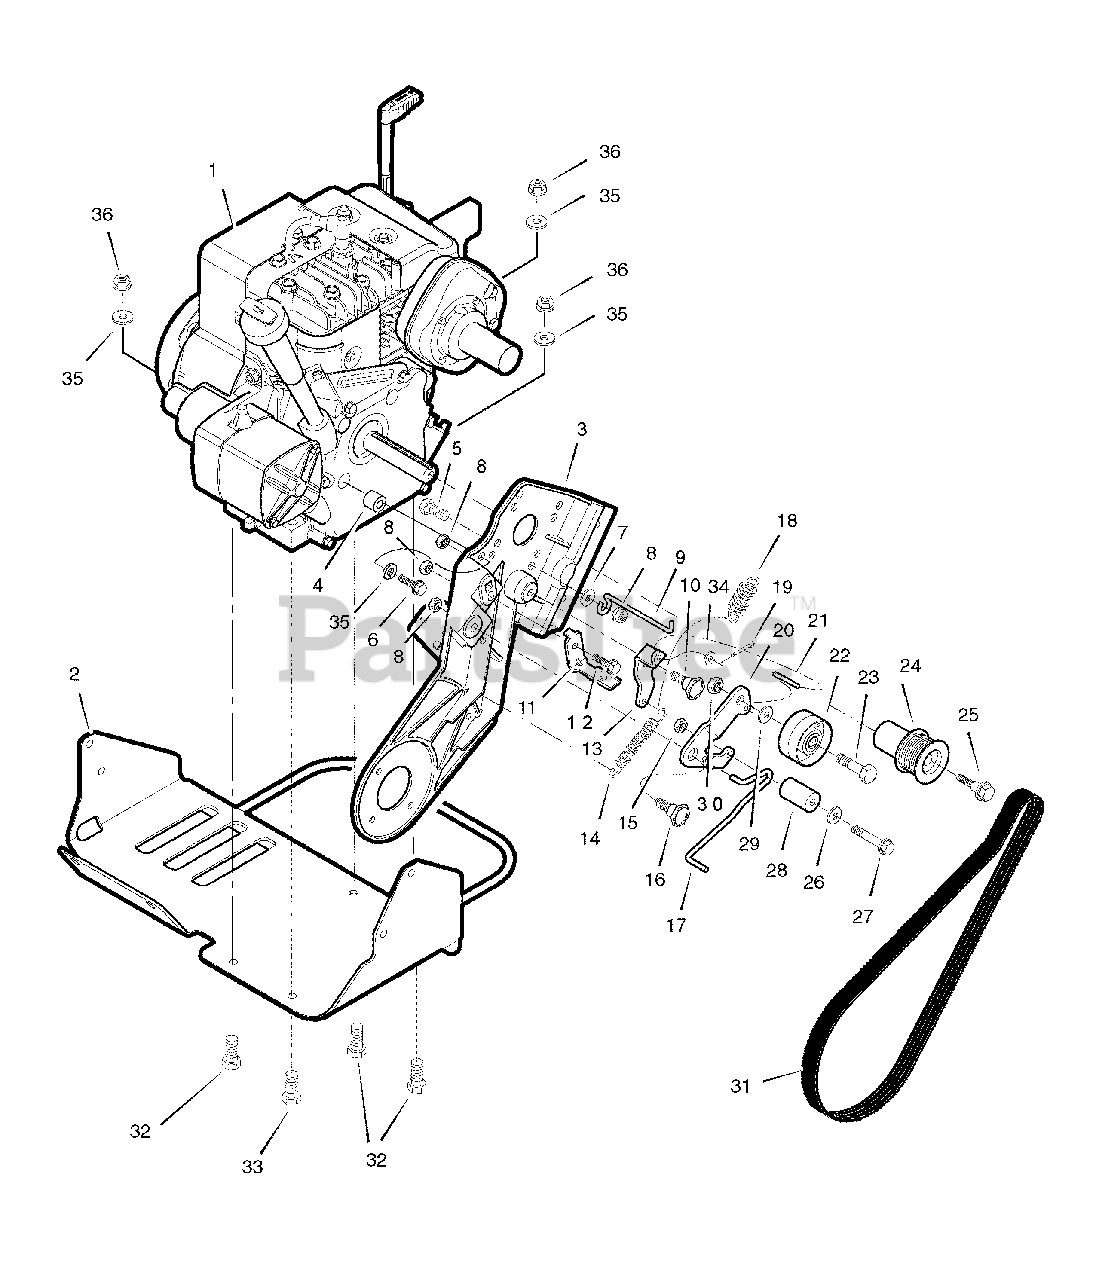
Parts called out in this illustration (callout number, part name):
1	* ENGINE, 5HP 4CY B&S Model 09A413-0202-E1
1	* ENGINE, 5HP 4CY B&S Model 09A413-0203-E1
2	CRADLE ASSEMBLY, Engine
3	FRAME, Left Hand
4	ANTIVIBRATION MOUNT, Engine
5	BOLT, Hex 5/16-18 x 0865
6	BOLT, Hex 5/16-24 x 1.125
7	WASHER, Flat
8	LOCKNUT, Hex Center 5/16-18
9	GUIDE, Belt
10	BOLT, Hex Head Shank 5/16-1/2 x 11/64
11	PAD, Brake
12	SCREW, 1/4-20 x 5/8
13	IDLER, Arm Pivot
14	SPRING, Extension 3/8 O.D. X .039W
15	NUT, Hex 1/4-20
16	BOLT
17	WIRE, Brake
18	SPRING, Extension .75 O.D. x .06
19	PIN, Cotter
20	ARM, Idler
21	ROD, Clutch Linkage
22	PULLEY, Idler
23	SCREW, 3/8-16 x 1.50
24	PULLEY, Model 9 Engine
25	BOLT, Engine Pulley
26	WASHER, Flat
27	SCREW, 1/4-20 x 2.00
28	PINCH ROLLER
29	WASHER, Flat
30	NUT, Hex
31	BELT, Drive
32	BOLT, Hex 5/16-18
33	SCREW, 3/8-16 x 1.00
34	WASHER, Flat
35	LOCKWASHER, Split
36	NUT, 5/16-18
